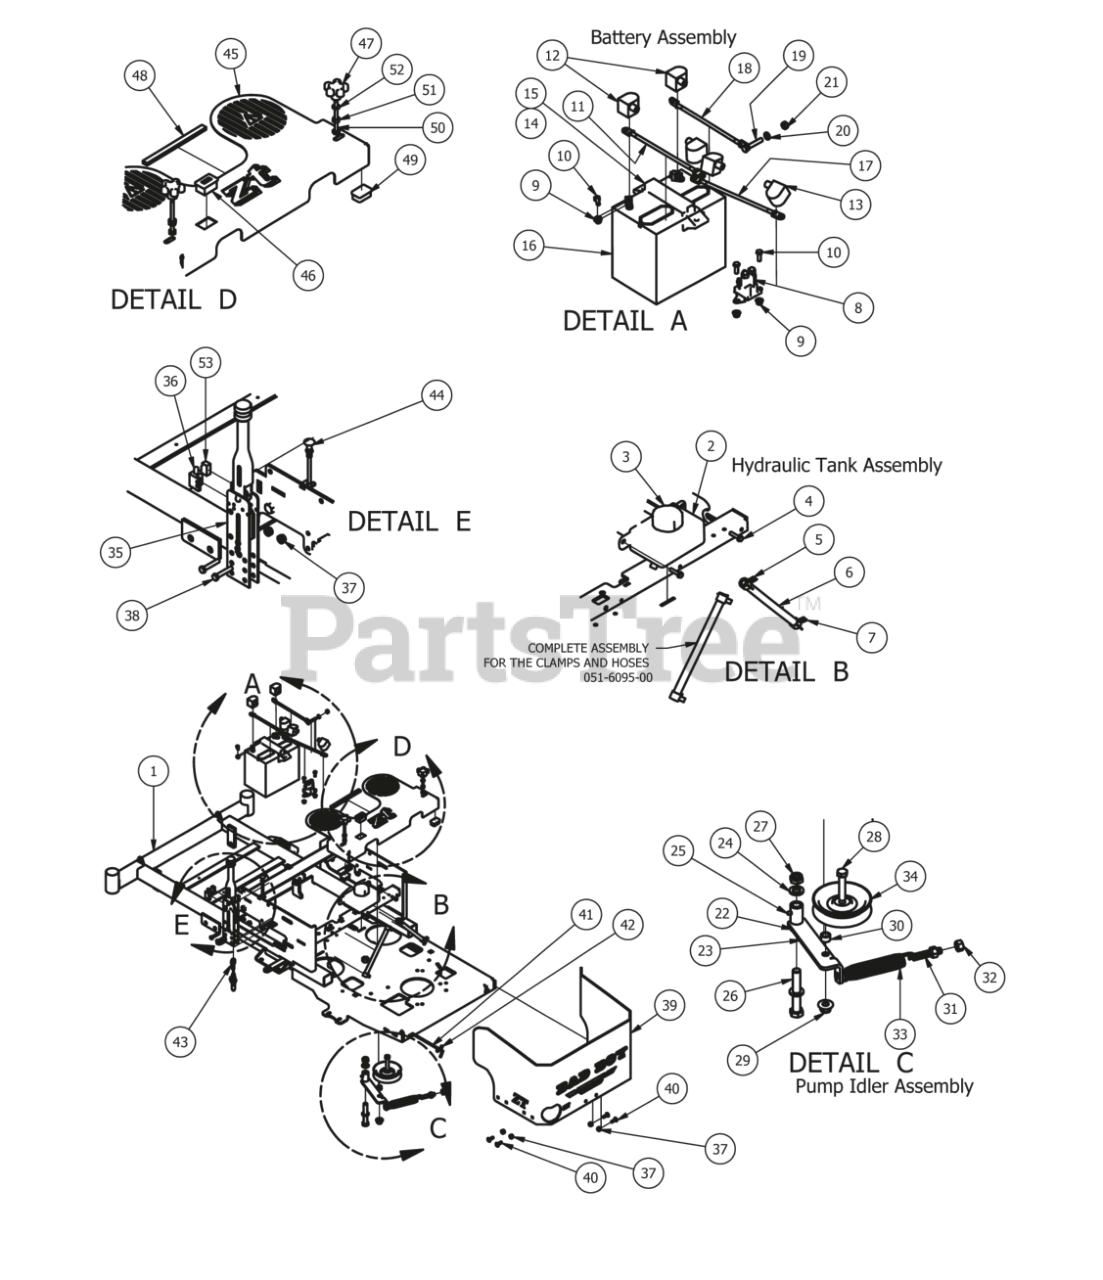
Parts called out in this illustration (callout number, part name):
2	ZT Hydraulic Tank
3	Hydraulic Tank Cap
4	1/4 x 1 Hex Head tek screw
5	3/8 hose clamp
6	3/8 clear hose price per foot
7	1/2 Hose Clamp
9	1/4-20 Hex Flange Nuts Zinc w/Serrations
10	1/4-20 x 3/4 GR 5 Hex Bolts Zinc
11	12 in red battery cable
12	Black Boot For ground cable
14	Hold Down Assembly
15	Battery Hold Down
16	ZT Battery
17	24 in red battery cable
18	Ground Cable
19	5/16" x 1 3/4" Hex Bolt
20	5/16" Lock Washer
22	Pump Idler Assembly Components 23,25,28,29,30,34
23	Pump Idler Bracket
24	.635 ID Plastic Washer
25	1/4" Drive in Grease Fitting
26	5/8" x 4" Hex Bolt
27	5/8" Nylock (1/2 Jam)
28	1/2-13 x 2 3/4 GR 5 Bolt
29	1/2-13 Nylon Flange Nut-Orange
30	1/2 x 1/2 Spacer
31	All Thread-pump Idler Tensioner
32	1/2" Hex Nut
33	Deck Idler Spring
34	4 3/4" Idler Pulley
35	Brake Handle Kit
36	Safety Switch
37	5/16-18 Nylon Flange Nut
38	5/16" x 1 3/4" Hex Bolt
39	ZT Rear plate 26hp
40	5/16" x 1" Carriage Bolt
41	ZT Neutral level rod 2011
43	Brake Cable
45	ZT Fan Cover
46	Tachometer
47	5/16" Knob
48	Rubber Trim
49	Square 3/4 Plug- SQR07-1620
50	18x3 GR5 Hex bolt zink
52	5/16" Lock Washer
53	Brake Plunger Stop
